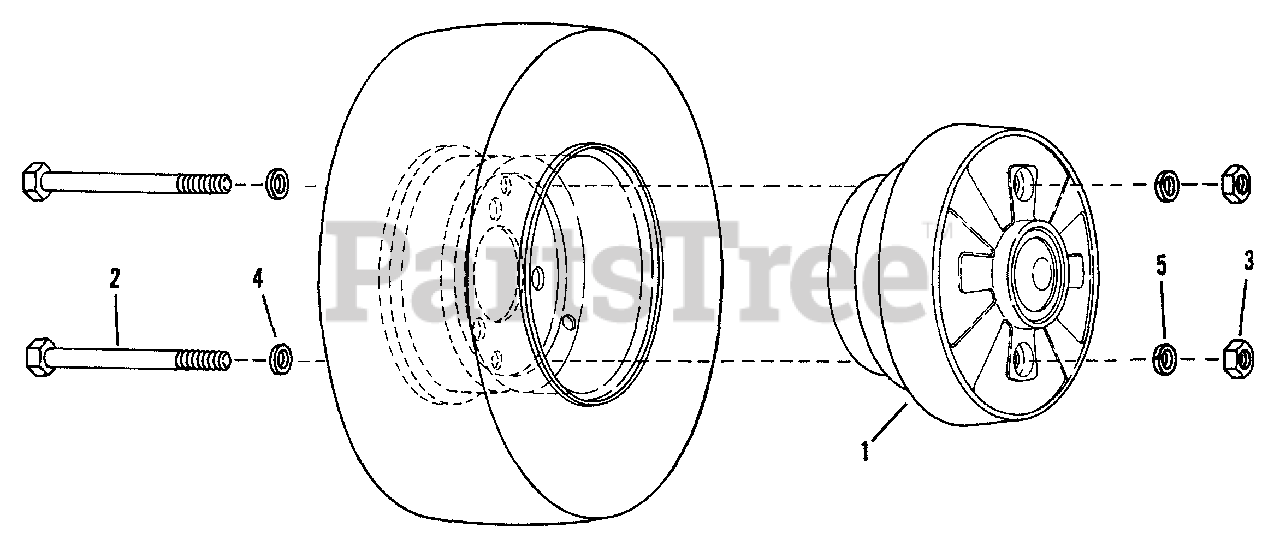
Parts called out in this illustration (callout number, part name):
1	WEIGHT, Wheel
2	SCREW, 3/8-16x7 1/2" Hex Head Cap
3	NUT, 3/8-16 Hex
4	WASHER, 3/8" Flat
5	WASHER, 3/8 Split Lock
